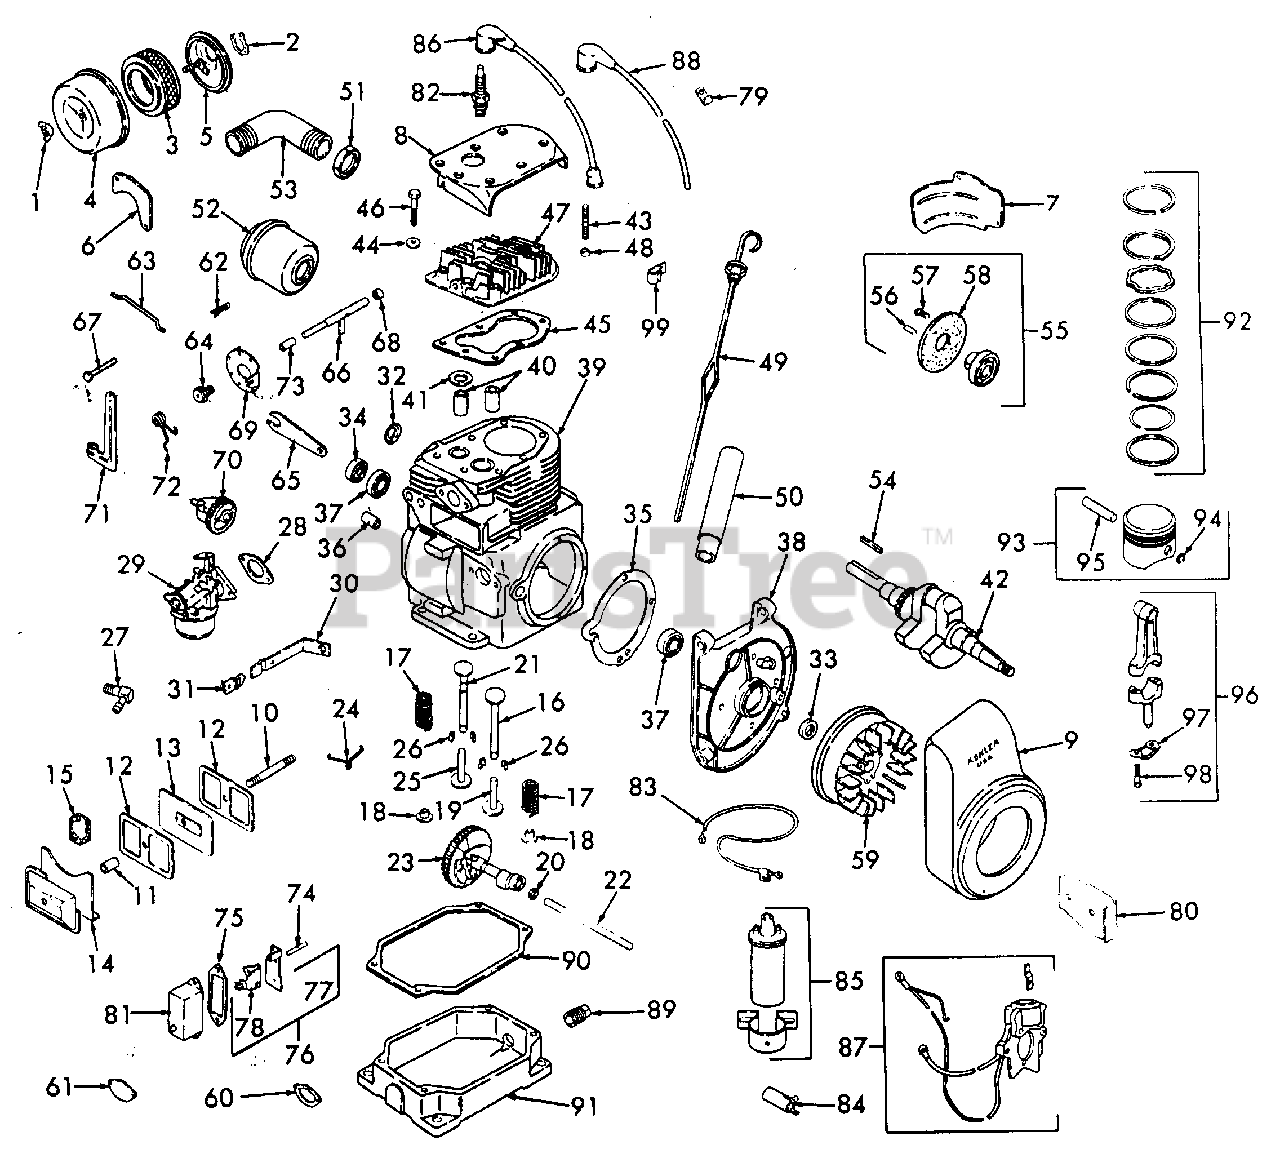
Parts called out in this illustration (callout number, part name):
1	Nut, 1/4-20 Wing
3	Element, Air Cleaner
4	Cover, Air Cleaner
5	Base, Air Cleaner
6	Baffle, Side Air
7	Baffle, Cylinder
8	Baffle, Head
9	Housing, Blower
10	Stud, Valve Cover
11	Seal, Breather
12	Gasket, Valve Cover
13	Breather Assy
14	Cover Assy, Valve
15	Filter
16	Valve, Intake
17	Spring, Valve
18	Retainer, Spring
19	Tappet, Intake Valve
20	Spacer, Camshaft, .005
21	Valve, Exhaust
22	Pin, Camshaft
23	Camshaft Assy
24	Spring, Actuating
25	Tappet, Exhaust Valve
26	Keeper, Spring
28	Gasket, Carburetor
29	Carburetor Assy
30	Bracket, Choke
32	Plug, Expansion
33	Seal, Front Oil
34	Seal, Rear Oil
36	Shaft, Governor
37	Bearing, Ball
38	Plate, Bearing
39	Mini Block Assy
40	Guide, Valve
41	Insert, Exhaust Valve
42	Crankshaft
43	Stud
45	Gasket, Head
46	Screw, 5/16-18 X 1-1/2 Hex Cap
47	Head, Cylinder
49	Dipstick Assy
50	Tube, Oil Fill
51	Nut, Lock
52	Muffler
53	Elbow, Exhaust
54	Key
55	Cup Assy, Flywheel Drive
56	Pin, 1/4 X 3/4
58	Screen
59	Flywheel
60	Gasket, Fuel Pump Pad
61	Cover, Fuel Pump Pad
62	Pin *
63	Linkage, Governor
64	Bushing, Governor
65	Bracket, Speed Control
66	Shaft, Governor
67	Pin, Governor Stop
68	Bearing, Needle
69	Disc, Regulating
70	Gear, Governor
71	Lever, Governor
72	Spring, Governor
73	Spacer
74	Rod, Breaker
75	Gasket, Cover
76	Breaker Assy
77	Bracket, Breaker Point
80	Bracket, Coil
81	Cover, Breaker
82	Plug, Spark
83	Lead, Breaker
84	Condenser
85	Coil, Ignition
86	Cable, High Tension
87	Stator Assy
88	Lead, Hi-Tension
89	Plug, 3/8 Pipe
92	Ring Set, Piston, Std
93	Piston Assy, Std
94	Retainer, Pin
95	Pin, Piston, Std
96	Rod Assy, Connecting, Std
97	Lock, Connecting Rod
98	Screw, Connecting Rod
99	Clip, Choke Cable
